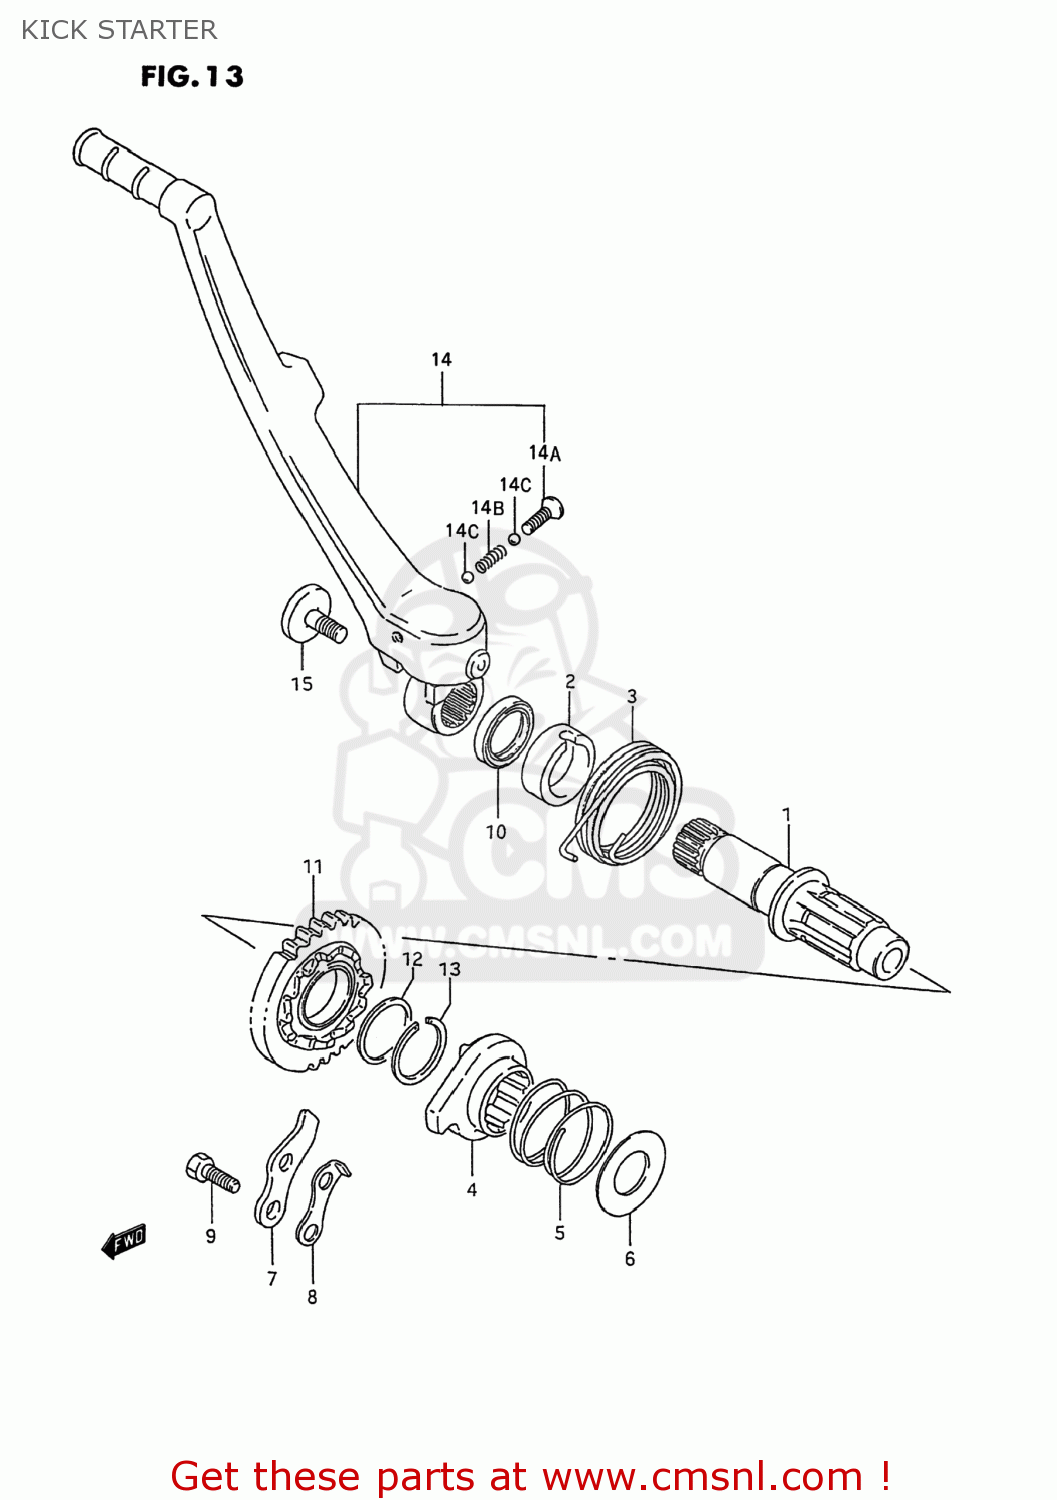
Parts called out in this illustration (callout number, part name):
1	SHAFT,KICK STARTER
2	GUIDE,KICK STARTER SHAFT
3	SPRING
4	STARTER,KICK
5	SPRING
6	WASHER
7	GUIDE,KICK STARTER
8	STOPPER,KICK STARTER
9	BOLT
10	SEAL,OIL(20X27X5)
11	GEAR COMP,KICK STARTER
12	SHIM
13	CIRCLIP
14	LEVER ASSEMBLY,KICK STARTER
14A	SCREW(6X27.5)
14B	SPRING
14C	BALL
15	BOLT(8X14)
